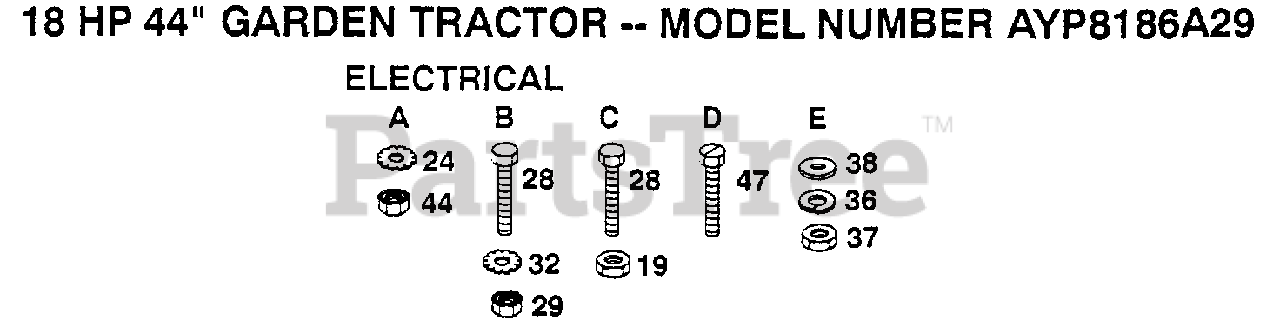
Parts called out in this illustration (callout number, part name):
28	BOLT
29	NUT
38	WASHER
44	NUT
47	SCREW
